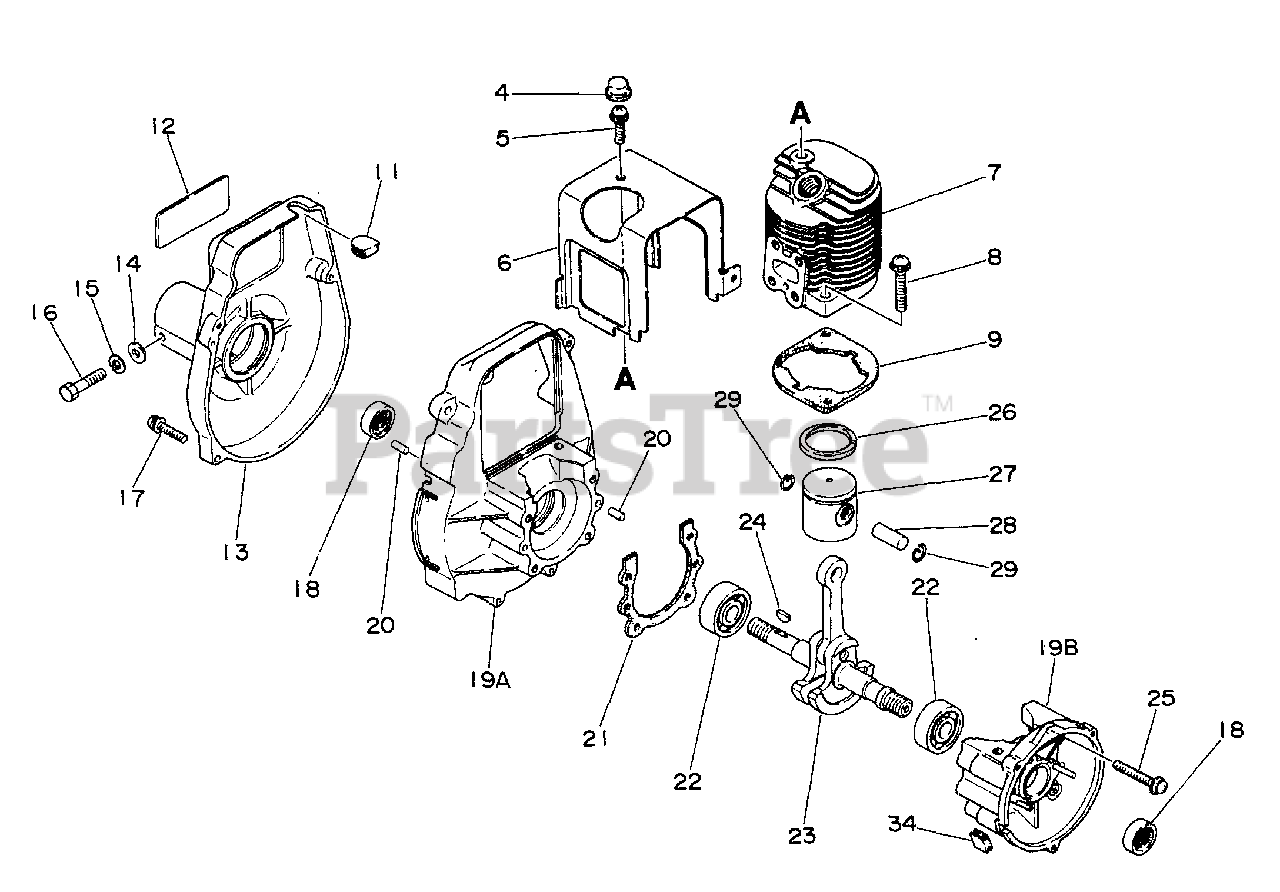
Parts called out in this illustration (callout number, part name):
4	SCREW - SOCKET HEAD CAP
5	SCREW 5×10
6	COVER, ENGINE
7	CYLINDER
8	SCREW 6×20
9	GASKET, CYLINDER
11	PLUG
12	LABEL, MODEL
13	COVER, FAN
14	WASHER, FLAT 5.5×10×0.8
15	WASHER, SPRING 5
16	BOLT - 5×20
17	SCREW 4×20
18	SEAL, OIL
19	CRANKCASE KIT
19A	CRANKCASE KIT
19B	CRANKCASE KIT
20	PIN, LOCATING 4
21	GASKET, CRANKCASE
22	BEARING, BALL 6200
23	CRANKSHAFT
25	SCREW 5×30
26	RING, PISTON
27	PISTON
28	PIN, PISTON
29	RING, SNAP
34	PLUG
